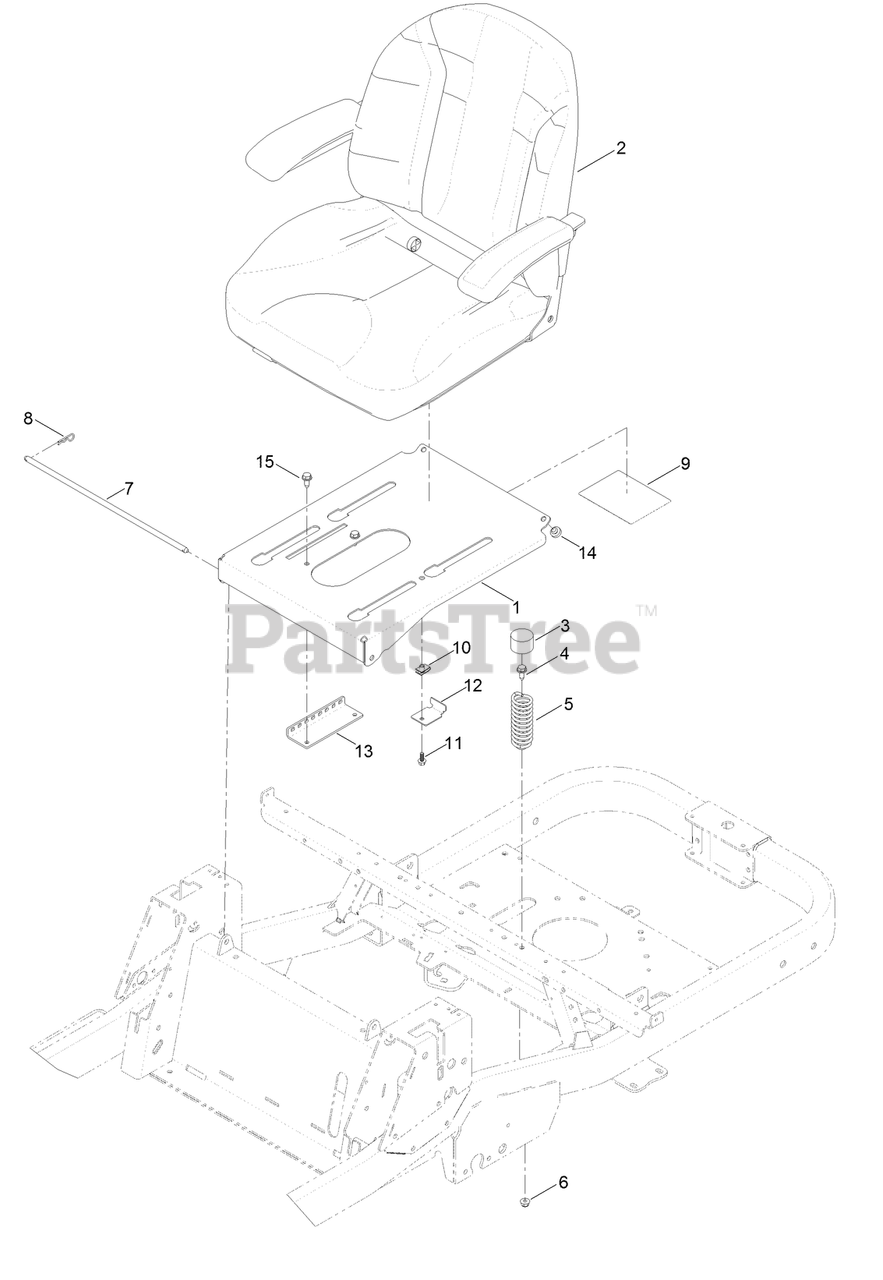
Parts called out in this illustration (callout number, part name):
1	PAN-SEAT
2	SEAT ASM
3	CAP-PROTECTOR
4	SCREW-HHF
5	SPRING-COMPRESSION
6	NUT-HF, NI
7	ROD-STOP
8	PIN-COTTER
9	DECAL-MAINTENANCE
11	SCREW-HHF
12	BRACKET-STOP, SEAT
13	BRACKET-LATCH, SEAT
14	BUMPER
15	SCREW-HWHTF
